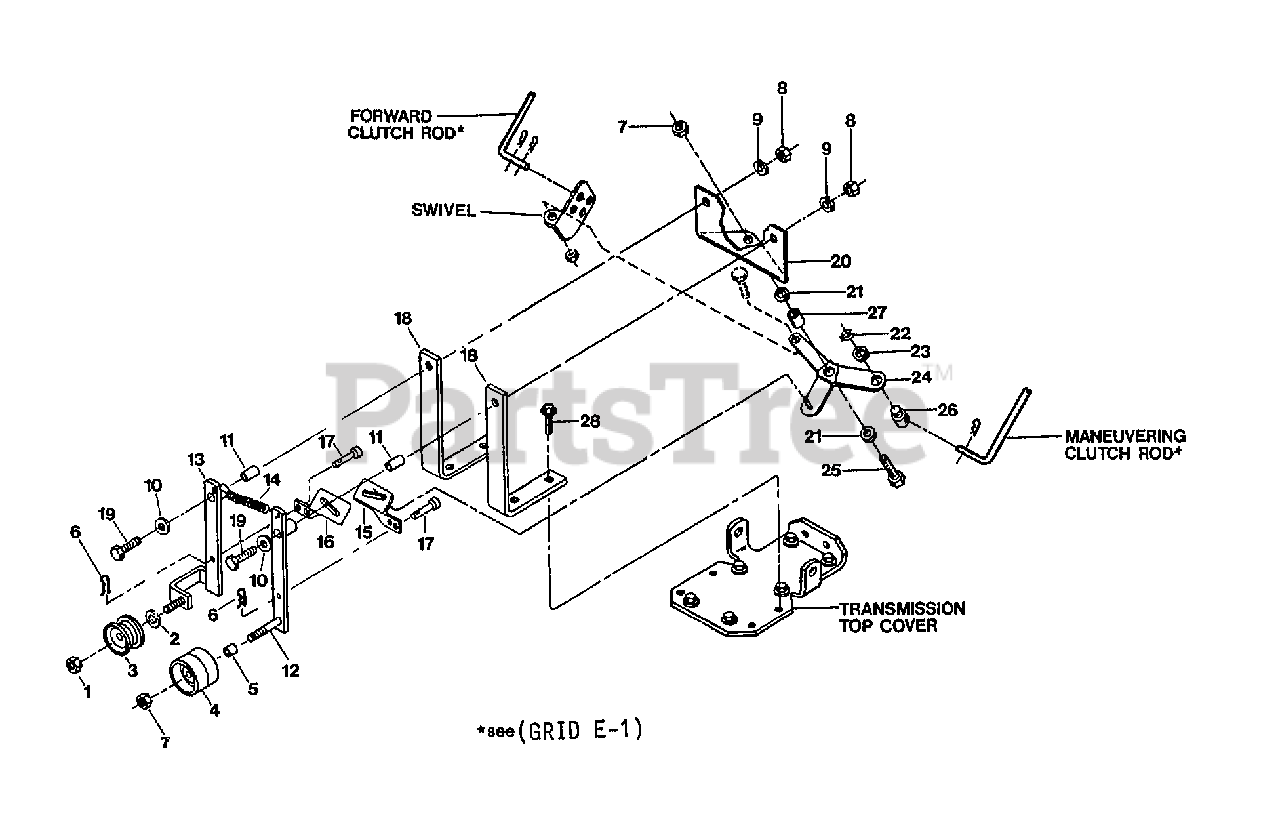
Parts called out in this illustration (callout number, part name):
1	NUT-LOCK 3/8-16 NYLON ZP
2	BUSHING-.54X.38X.08
3	IDLER-REV
3	PULLEY-IDLER REVERSE
4	PULLEY-FWD IDLER
5	BUSHING-.5X.375X.3
6	PIN-CLIP .08
7	NUT-H/LK 3/8-16
8	NUT-HEX 5/16-18 ZP
9	WASHER-LK .312 ZP
10	WASHER-#.75X.32X.09 ZP
11	BUSHING-.438X.323X.712
12	ARM-IDLER FWD PNT
13	IDLER-REV
13	ARM-IDLER REV RED
14	SPRING-.436 X 3.25
15	LINK-FWD
17	PIN-CLEVIS .375X.719 ZP
18	MOUNT BAR-PNT (20691)
19	SCR-HH 5/16-18X2.25 G5ZP
20	SHIFT BASE-OPC PNT
21	SPACER-.88X.385X.09 ZP
22	RING-KLIP .500 ZINC
23	WASHER-#.88X.51X.063 ZP
24	BELLCRANK-OPC PNT
25	SCR-HH 3/8-16X1.25
26	PIVOT-ROD
27	BUSHING-.5X.38X.4
28	SCR-HFLK 5/16-18X1.00 ZP
